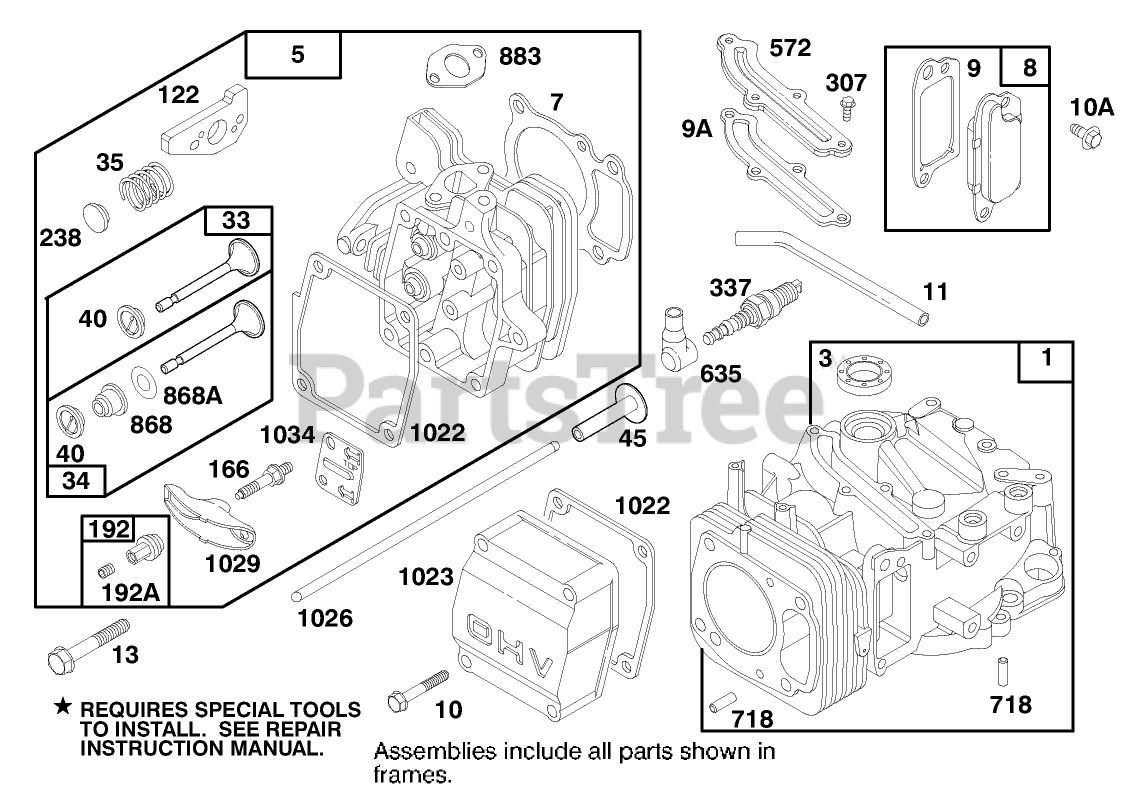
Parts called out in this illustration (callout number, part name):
98A	SPEED ADJUST. SCREW ASM
163	AIR CLEANER GASKET
188	Screw-Cap
201	GOVERNOR LINK
209	GOVERNOR SPRING
529	TUBE - BREATHER
535	FILTER ELEMENT
618	RETURN SPRING
620	CARBURETOR BRACKET
621	STOP SWITCH
966	AIR CLEANER BASE
968	AIR CLEANER COVER
969	AIR CLEANER SCREW
971	AIR CLEANER SCREW
